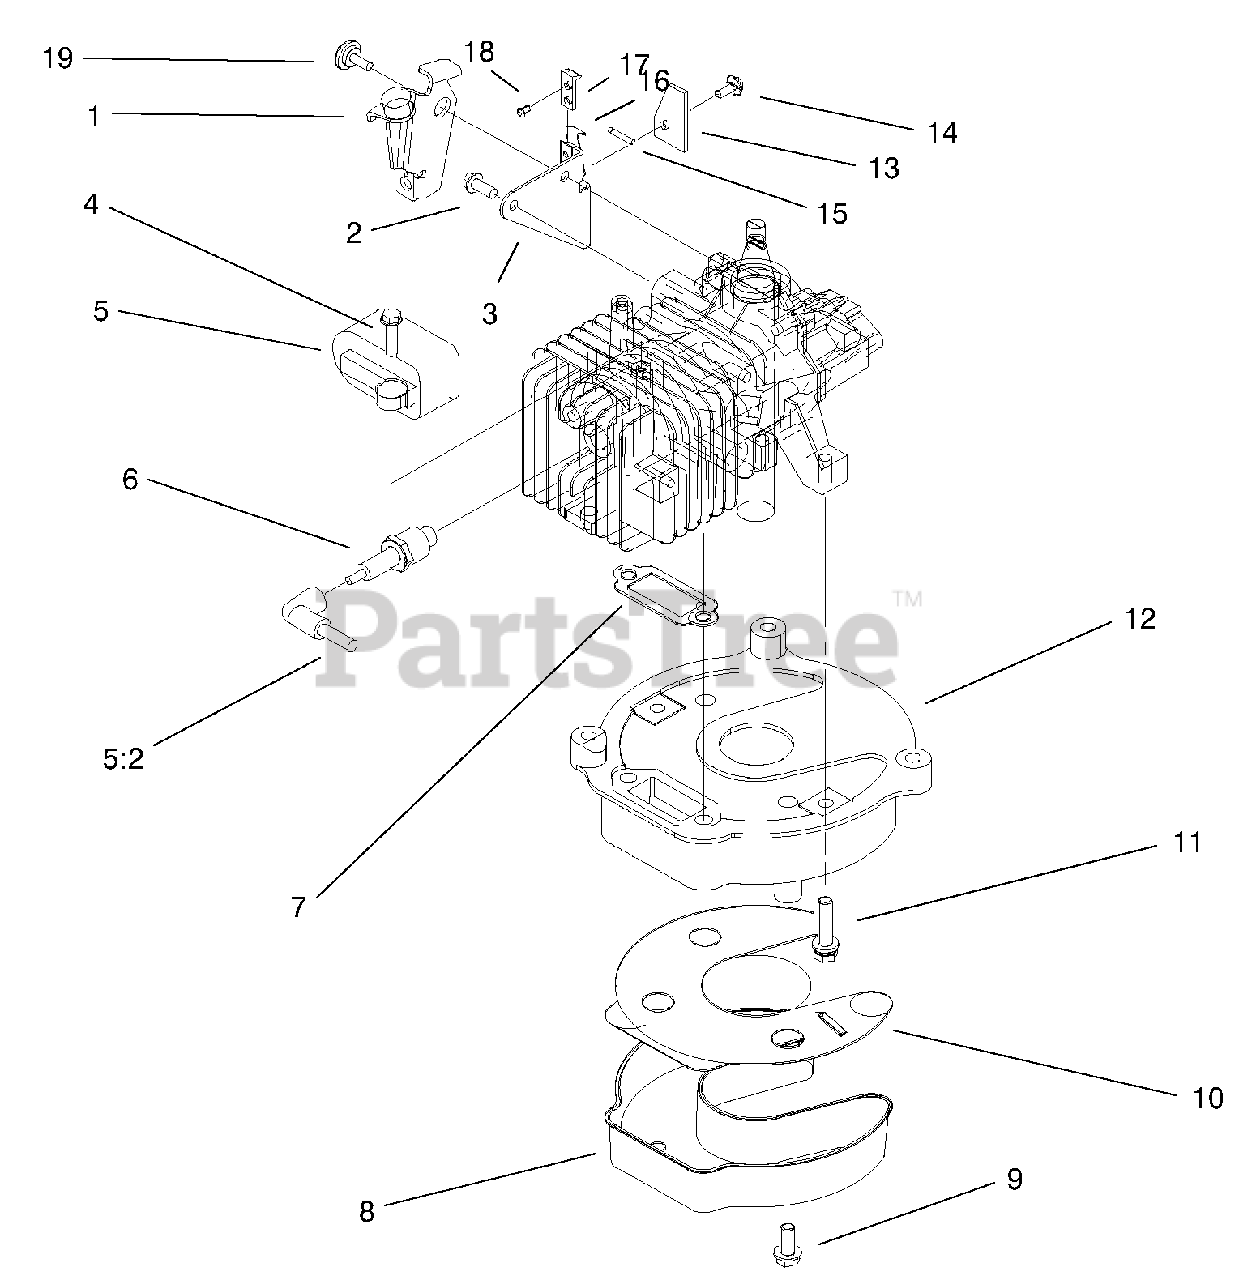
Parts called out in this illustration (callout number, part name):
1	Brake Plate ASM
2	Screw
3	Plate-Brake
5	Module-Ignition
5:2	Lead-High Tension
6	Spark Plug (Service)
7	Gasket-Exh
8	Muffler Cover
10	Baffle-Muffler
12	Plate-Muffler
13	Stop-Ground Strap
15	Elec Lead Ay
16	Strap-Ground
17	Strap-Insulation
18	Rivet-Plastic
19	Screw-shoulder
